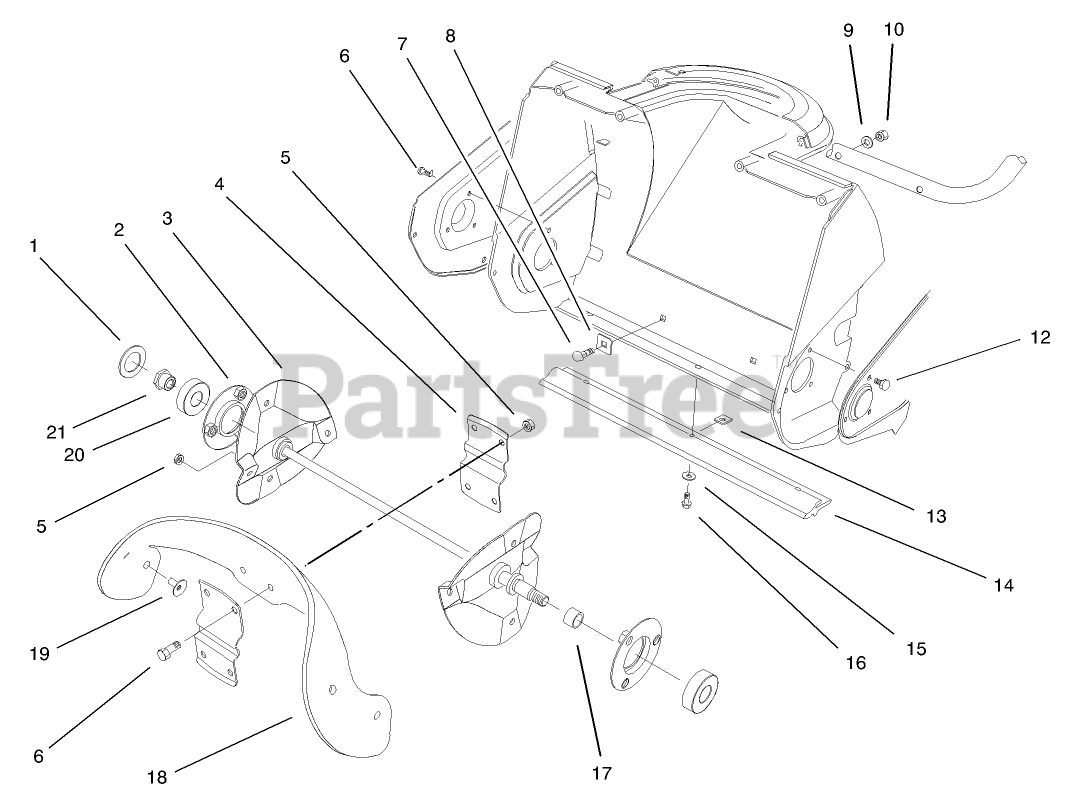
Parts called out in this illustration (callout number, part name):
1	WASHER-RUBBER
3	ROTOR SHAFT ASM
4	SUPPORT-ROTOR
5	NUT-LOCK, NI
6	SCREW-HHF
7	SCREW-CARR
8	WASHER-SQUARE
9	WASHER
10	NUT-LOCK, NI
12	SCREW-HH
13	NUT-CLIP, U
14	SCRAPER
15	WASHER-FLAT
16	SCREW-HWHTF
17	SPACER
18	BLADE-ROTOR
19	SCREW
20	BEARING-BALL
